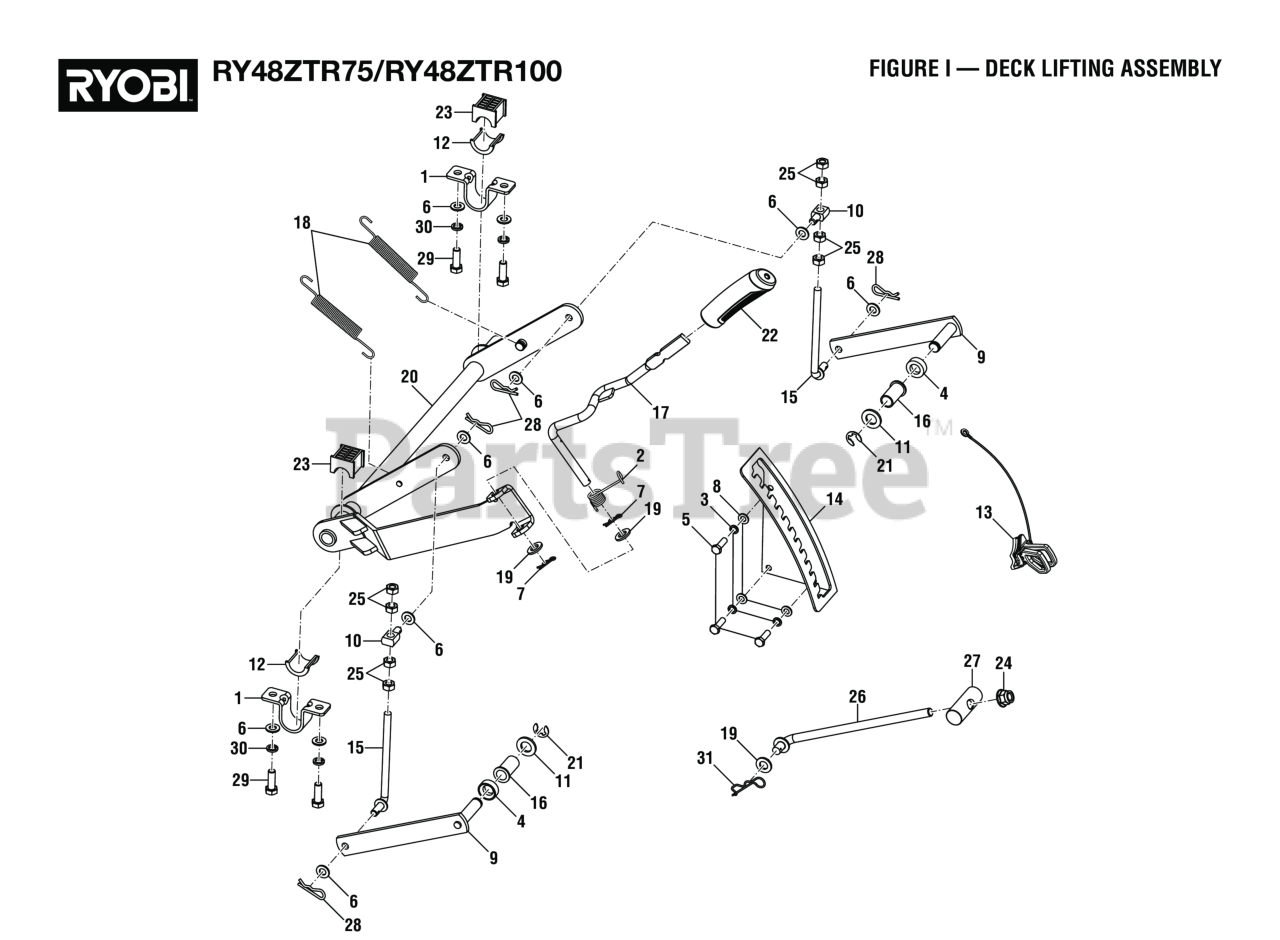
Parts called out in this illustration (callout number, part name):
1	Deck Lift Axle Mount
2	Deck Lift Lever Torsion Spring
3	Lock Washer (OD9.8 x ID8.5 x 5t)
4	Deck Lift Linkage Spacer
5	Bolt (M8 x 25 mm, Hex Hd.)
6	Washer (OD20 x ID10.5 x 2t)
7	Cotter Pin (12 mm)
8	Washer (OD16 x ID8.4 x 1.6t)
9	Deck Lift Linkage
10	Hanger Stud, ZTR
11	Washer (OD30 x ID17 x 3t)
12	Deck Lift Axle Bushing, Bottom
13	Cut Height Memory Plug
14	Detent Plate
15	J Hook, Deck Hanger
16	Deck Lift Linkage Bushing
17	Deck Lift Lever
18	Deck Lift Spring
19	Washer (OD24 x ID13 x 2.5t)
20	Deck Lift Linkage and Axle Assembly
21	E-Ring Clip (12 mm)
22	Decklift Handle
23	Deck Lift Axle Bushing,Top
24	Flange Nut (M12)
25	Nut (M10)
26	J Hook, Front Deck Hanger
27	Front Deck Hanger Pivot Axle
28	Cotter Pin
29	Hex Head (M10 x 30 mm)
30	Lock Washer (M10)
31	Hinge Cotter Pin
